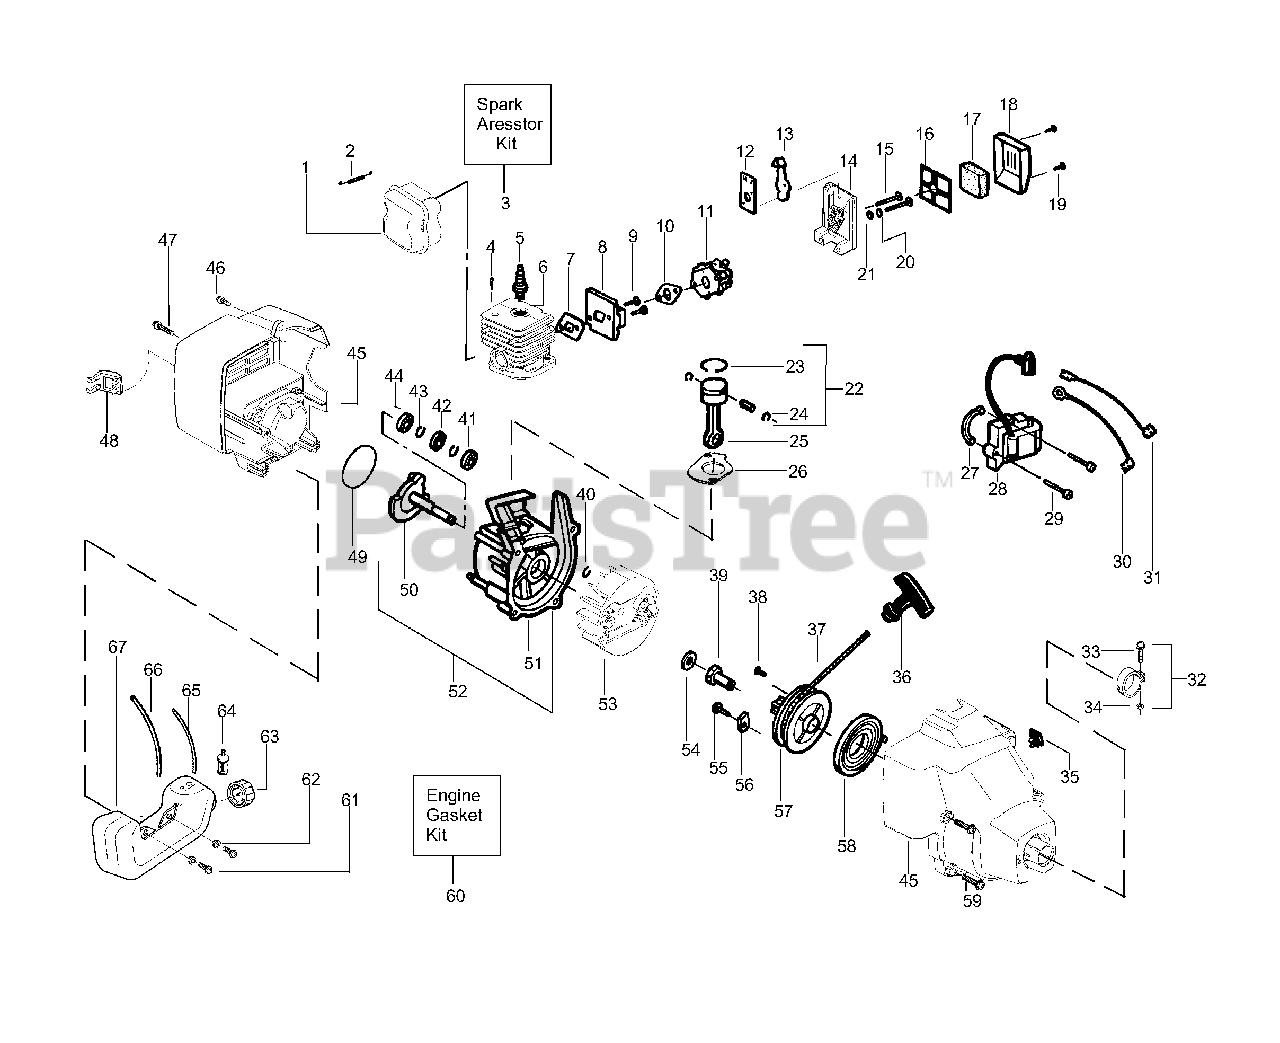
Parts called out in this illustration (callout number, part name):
1	Kit - Muffler
2	Spring-Muffler
3	Kit-Spark Arrestor
4	Screw-Cylinder
5	Spark Plug (RCJ 8Y)
6	Kit - Cylinder
7	Gasket-Cylind./Carb.
8	Adapter-Carb.
10	Gasket-Carb.
11	Kit - Carburetor Ass'y
12	Choke Plate Mounting
13	Shutter-Choke
16	Plate - Filter Support
17	Foam-Air Filter
18	Cover-Air Filter
20	Spacer-Choke
22	Kit - Piston
23	Piston Ring
24	Retainer-Piston Pin
25	Assy-Connecting Rod
26	Gasket-Cylinder
27	Spacer-Module
28	Ignition Module
30	Assy-Ground Wire
31	Assy-Leadwire
32	Assy-Nose Cone Clamp
33	Screw-Nose Cone
34	Nut-Nose Cone
35	Kit-On/Off Switch
36	Handle-Starter
37	Kit - Rope
39	Coupling-Drive
40	Retain. Ring-C'shaft
41	Outer Bearing
42	C'case Seal
43	Retainer Ring-C'case
44	Inner Bearing
45	Assy.-Fan Hsg/Shroud
47	Screw
48	Guard-Muffler
49	O-Ring-C'case/Shrd
50	Assy-Crankshaft
51	Assy-Crankcase
52	Assy-C'case & C'shaft
53	Assy-Flywheel
54	Washer-Flat
56	Retainer-Can
57	Kit-Starter Pulley
58	Spring-Starter
59	Screw
60	Kit-Engine Gasket
63	Assy-Fuel Cap
64	Assy-Fuel Pickup
65	Kit-Fuel Line (Small)
66	Kit-Fuel Line (Large)
67	Assy-Fuel Tank
